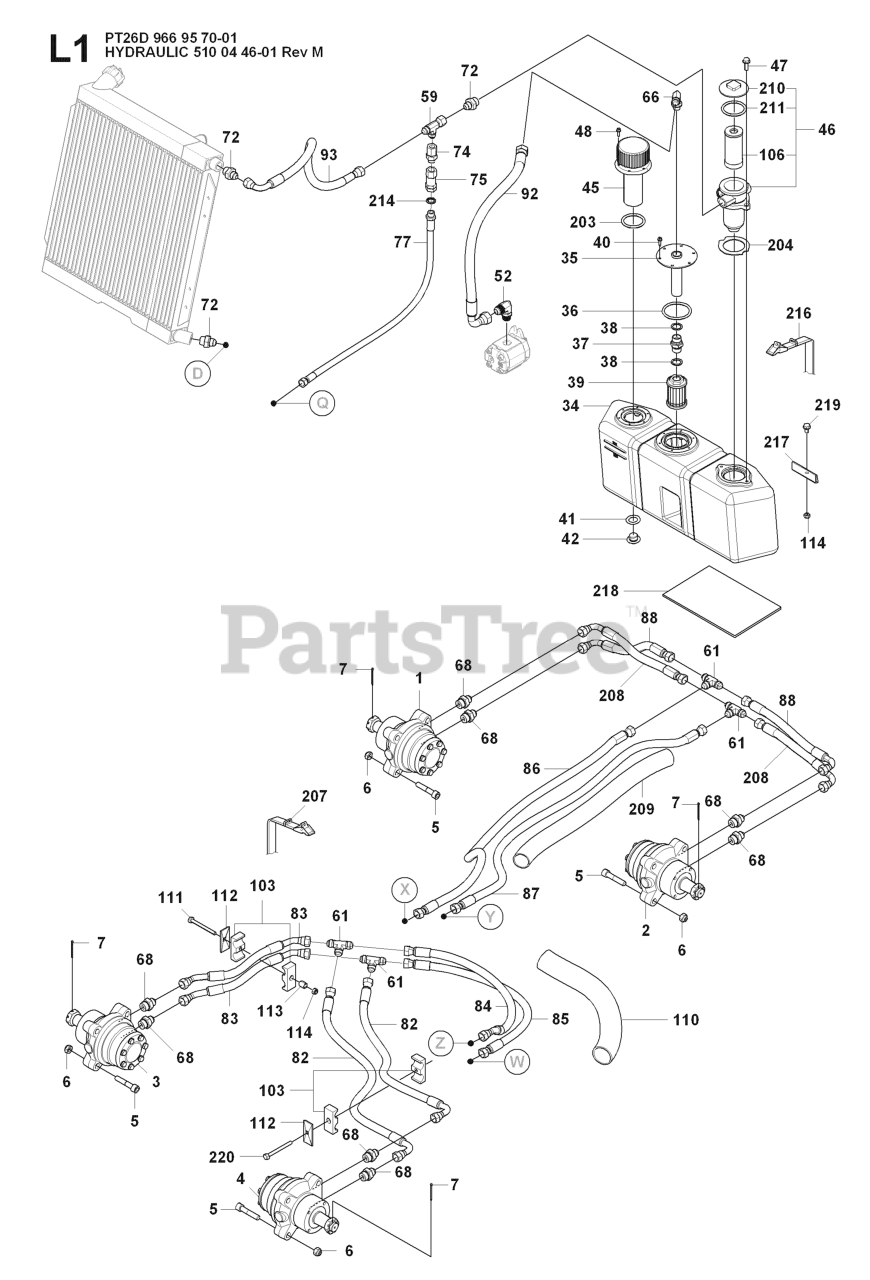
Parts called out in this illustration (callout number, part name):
1	WHEEL MOTOR 125 CW
2	WHEEL MOTOR 125 CCW
3	WHEEL MOTOR 160 CW
4	WHEEL MOTOR 160 CCW
7	COTTER PIN
36	O-RING 61.2X5.7 NITRIL
37	PIPE FITTING G STRAIGHT 1/2-1/
39	FILTER PUMP SUCTION, AWD
46	FILTER HOLDER
61	PIPE FITTING JIC T 3/4"
74	PIPE FITTING JIC-BSPP STRAIGHT
75	CHECK VALVE 2BAR
114	LOCKNUT M8
203	O-RING 47.2X5.7 NITRIL
209	HOSE GUARD D=43 L=500
210	FILTER HOLDER
211	O-RING 47.2X5.7 NITRIL
